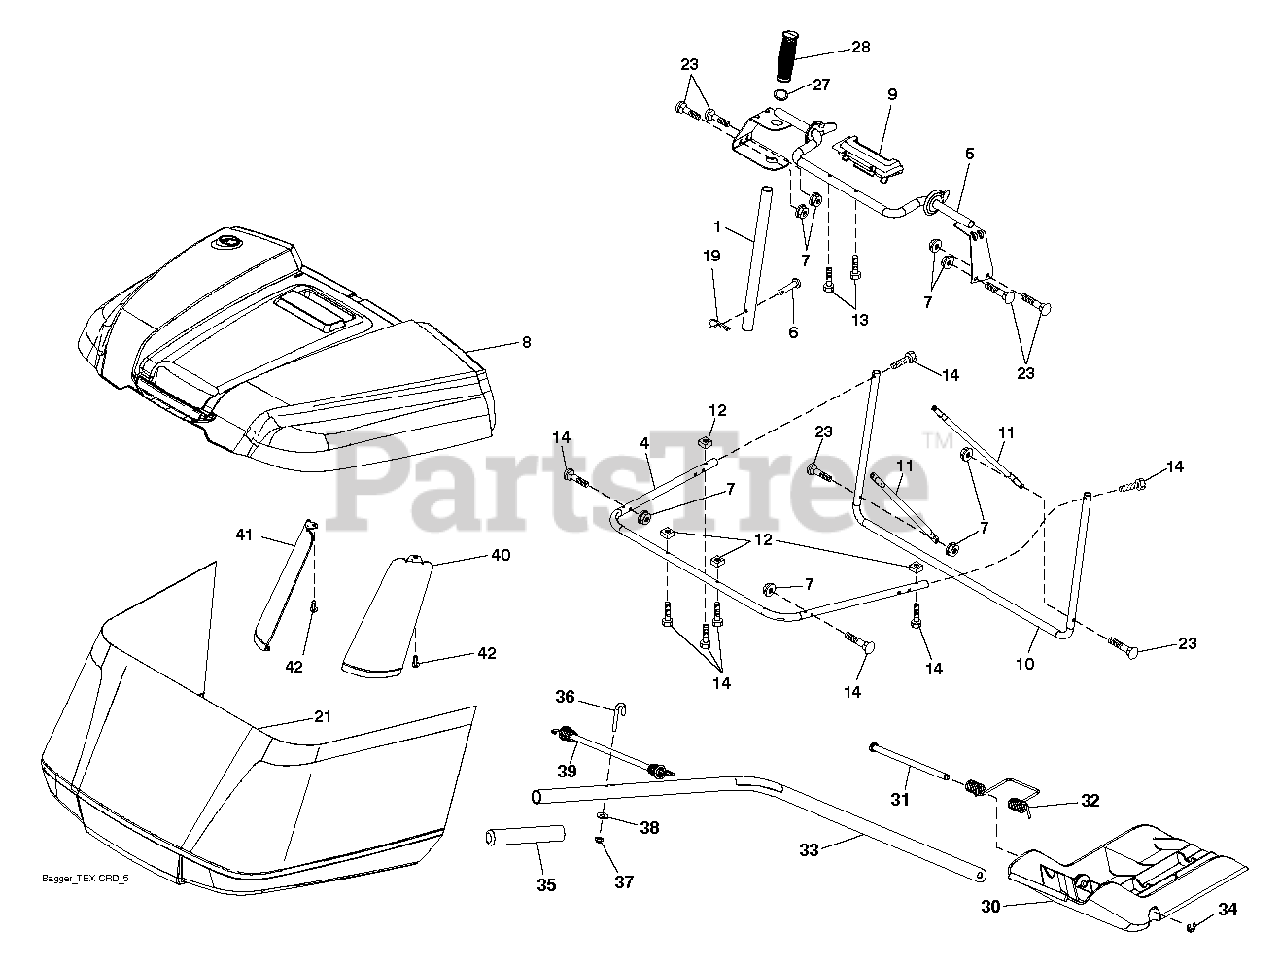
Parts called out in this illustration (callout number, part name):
1	TUBE.PNT.HDL.BAGGER.
6	RIVET,DRILLED
7	NUT T
19	PIN.COTTER.5/16.BOW TI
28	GRIP.HANDLE.BLACK
34	E-RING.5/16"
38	WASHER
